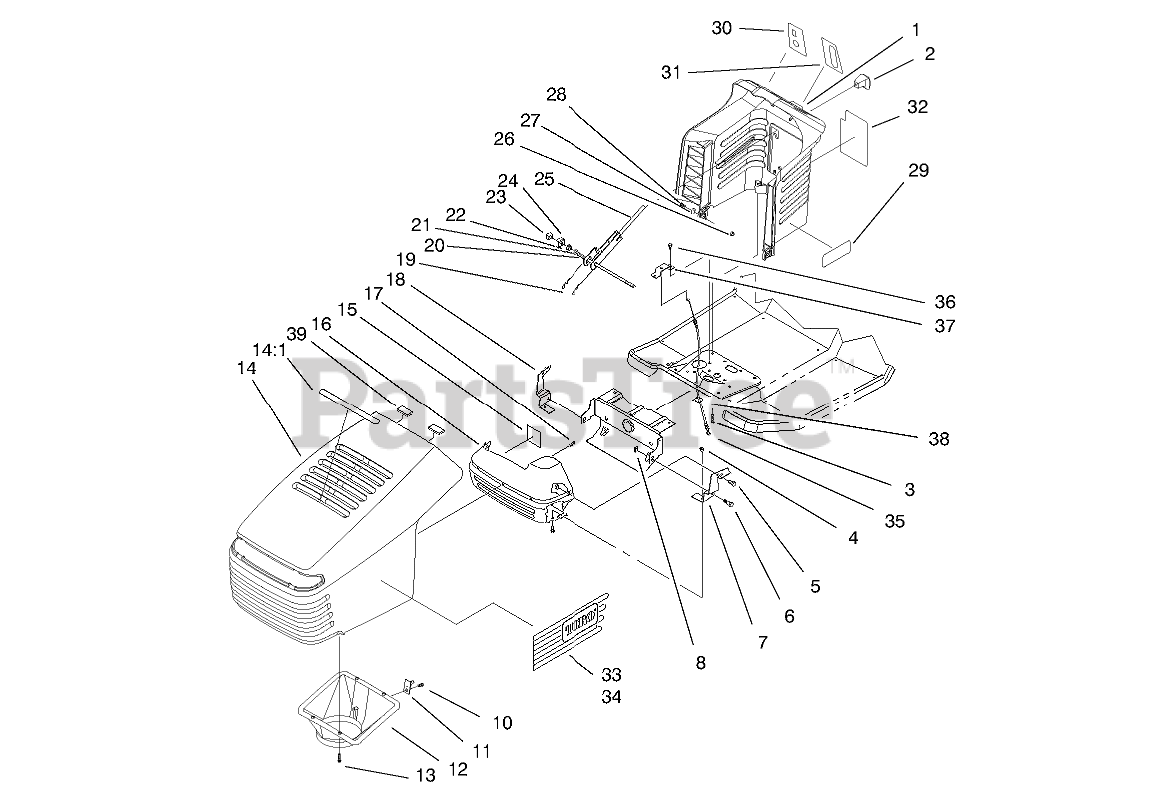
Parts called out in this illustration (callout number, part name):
1	Tower-Steering
2	KNOB-SHIFT
3	SCREW-HWH
4	NUT-LOCK, NI
5	SCREW-HH
6	BOLT-SHOULDER
7	BRACKET-PIVOT, LH HOOD
8	NUT-RETAINER
10	SCREW-HWH
11	LATCH-PIN
12	DUCT-AIR
13	SCREW-PLASTITE
14	HOOD ASM
14:1	DECAL-AIR DUCT
14:2	Packaging Instructions
15	TAPE-FOIL
16	SHIELD-HEAT
17	SCREW-PLASTITE
18	BRACKET-PIVOT, RH HOOD
19	PIN-COTTER
20	ROD-TOWER PIVOT
21	WASHER-FLAT
22	NUT-FLANGE
23	NUT-WEDGE
24	ROD-CLAMP PIVOT
25	LEVER-DECK, ENGAGE
26	NUT-LOCK, NI
27	WASHER-PLAIN
28	SCREW-HH
29	DECAL - TOWER
30	DECAL-IGNITION/LIGHTS
31	DECAL
32	DECAL-DECK, ENGAGE
33	DECAL - HOOD LEFT
34	DECAL - HOOD RIGHT
35	Cable-Deck Engage
36	SCREW-HWH
37	BRACKET-CABLE, UPPER
39	FOAM-HOOD
